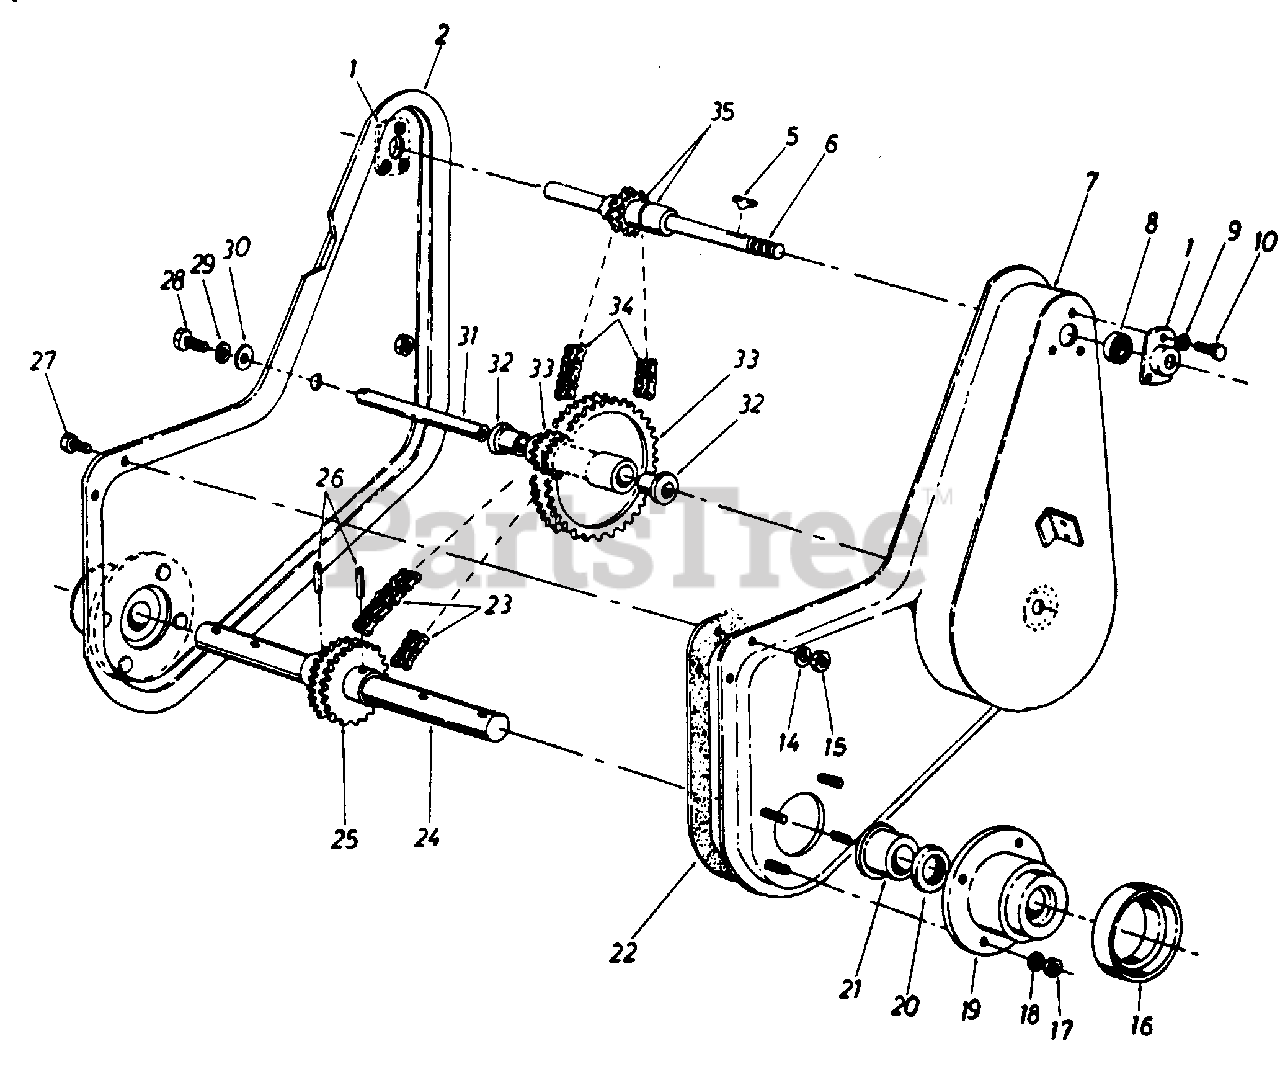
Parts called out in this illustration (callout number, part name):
1	Bearing Housing l.375" Dia.
6	Input Shaft Assembly
9	L-Wash. 1/4" I.D.
10	Hex Bolt 1/4-20 x .62" Lg.
14	L-Wash. 1/4" I.D.
15	Hex Cent. L-Nut 1/4-20 Thd.
16	Dust Cap Cover
17	Hex Cent. L-Nut 5/16-18 Thd.
18	L-Wash. 5/16" I.D.
19	Cast Bearing Housing
20	Oil Seal
21	Flange Bearing 1.25" I.D. x 1 75" O.D.
22	Gasket
23	Roller Chain #40-2 x 34.0" Lg.
24	Tine Shaft
25	Double Sprocket T242 Teeth 0 0 1/2" Pitch
26	Spiral Pin 3/8 Dia. x 2.00 Lg.
27	Hex Bolt 1/4-20 x .62" Lg.
28	Hex Bolt 5/16-18 x .75" L9.
29	L-Wash. 5/16" I.D.
30	Fl-Wash. 5/16 I.D.
31	Sprocket Shaft
32	Flange Bearing .62 I.D. x .75" O.D.
33	Double Sprocket Assembly
34	Roller Chain #35-2 x 36.75" Lg.
35	Spacer 5/8 I.D. x 7/8 O.D.
